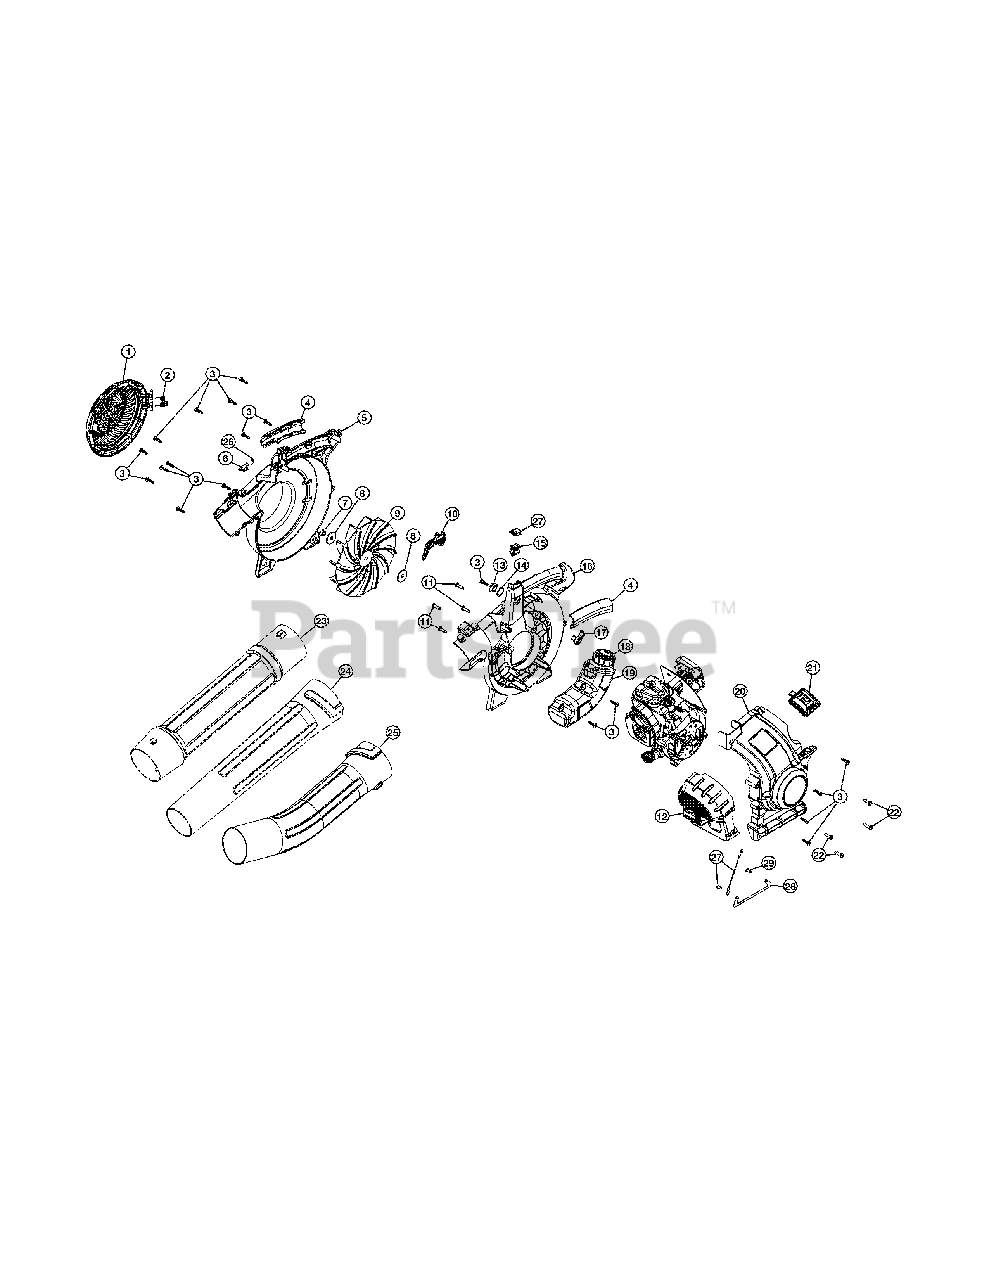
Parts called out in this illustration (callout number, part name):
1	Intake Cover
2	Spring
4	Handle Grips
5	Impeller Housing (Incl Ref No. 4)
6	Latch Tube
8	Washer
9	Impeller
10	Throttle Trigger
11	Screw
12	Muffler Cover (Incl Ref No. 3)
13	Inner Trigger Lock
14	Wavey Washer
16	Impeller Housing (Incl Ref No. 4)
17	Outer Trigger Lock
18	Fuel Cap
19	Fuel Tank Assembly (Incl Ref No. 18)
20	Engine Cover Assembly (Incl Ref No. 3, 21 & 22)
21	Spark Plug Cover
23	Upper Tube
24	Lower Tube
25	Flare Tube
26	Latch Spring
27	Wire Ground
28	Strap Ground
29	Screw
